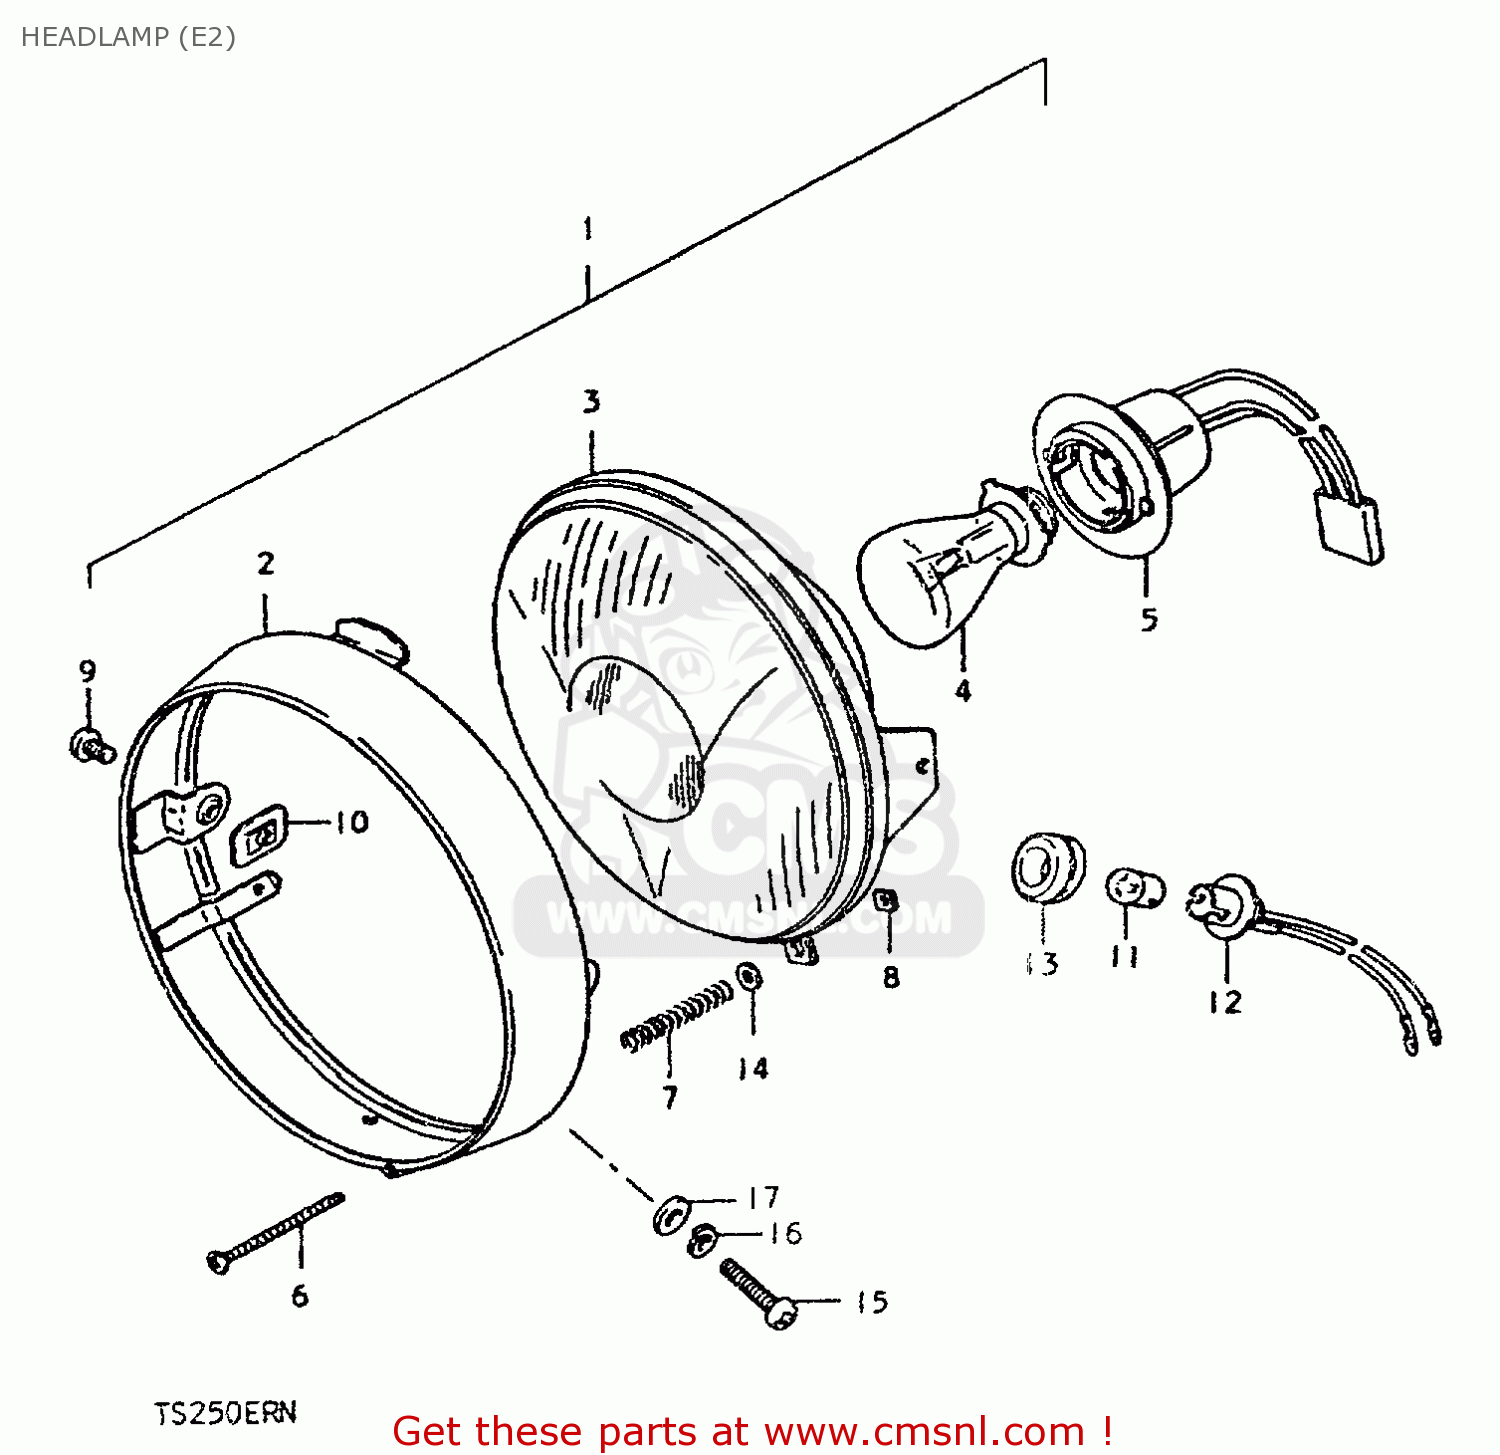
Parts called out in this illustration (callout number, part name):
1	HEADLAMP ASSY
2	RIM
3	UNIT
4	BULB(6V25/25W,STANLEY,A7007)
5	SOCKET,HEADLAMP
6	SCREW,HEADLAMP ADJUST
7	SPRING
8	NUT,HEADLAMP ADJUSTER
9	SCREW
10	NUT
11	BULB(6V/3W)
12	SOCKET
13	SEAL,PARKING BULB
14	WASHER
15	SCREW
16	LOCK WASHER
17	WASHER
